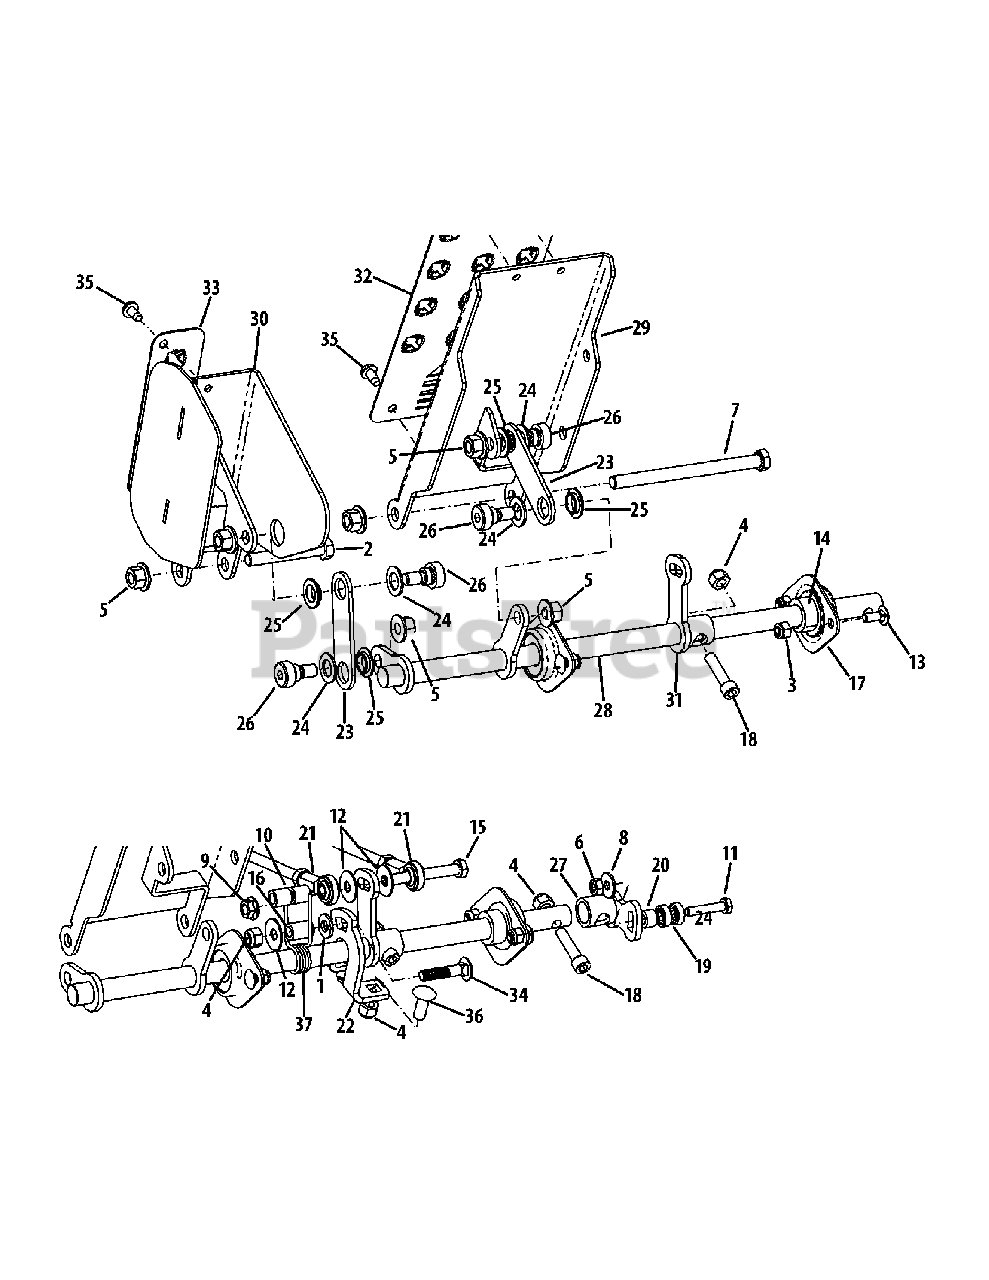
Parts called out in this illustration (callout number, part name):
1	Washer, .344 x .688 x .063
2	Hex Screw, 3/8-16 x 2.50
3	Nut, 1/4-20
4	Nut, 5/16-18
5	Flange Counter Lock Nut, 3/8-16
6	Counter Lock Nut, 1/4-20
7	Hex Screw, 3/8-16 x 5.00
8	Bell Washer, .265 x .75 x .062
9	Flange Counter Lock Nut, 5/16-18
10	Spacer, .315 x .500 x .520
11	Hex Screw, 1/4-20 x 1.25
12	Bell Washer, .325 x .930 x .045
13	Carriage Bolt, 1/4-20 x .620
14	Shaft Collar, .625 x 1.00 x .438
15	Hex Screw, 5/16-18 x 2.50
16	Spacer, .315 x .500 x .699
17	Flange Bearing
18	Screw, 5/16-18 x 1.25
19	Ball Bearing, .25 x .625 x .196
20	Spacer, .256 x .500 x .330
21	Speed Control Link Assembly
23	Pedal Control Link
24	Washer, .51 x .88 x .06
25	Flange Bearing, .502 x .875 x .180
26	Shoulder Bolt, 3/8-16 x .50 x .25
27	Lockout Hub Assembly
28	Pedal Bellcrank Assembly
29	Forward Pedal Assembly
30	Reverse Pedal Assembly
31	Control Arm Assembly
32	Forward Pedal Grip
33	Reverse Pedal Grip
34	Carriage Bolt, 5/16-18 x 1.50
35	Screw, 1/4-20 x .5
36	Carriage Bolt, 5/16-18 x .88
37	Torsion Spring, .66 x .56
